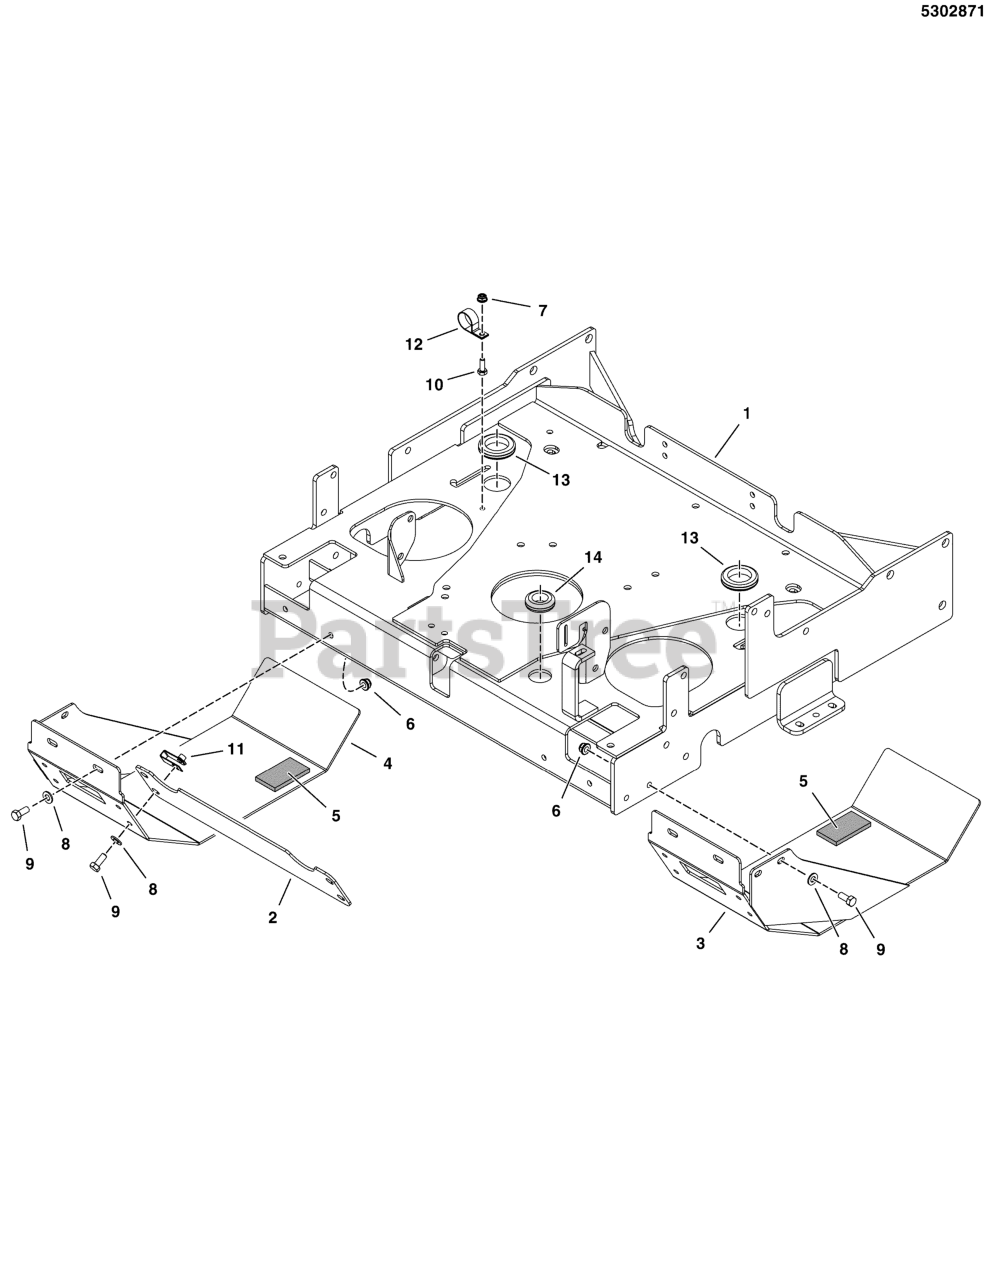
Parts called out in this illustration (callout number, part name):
1	WELD, ENGINE DECK, SW30 - RED
2	PLATE, REAR GUARD, SW30 - RED
3	WELD, SKID PLATE, RH - RED
4	WELD, SKID PLATE, LH - RED
5	PAD, RUBBER MOUNT, 1/4 MAT
6	NUT, 5/16-18 HEX NYLOCK FLANGE
7	NUT, 1/4-20 HEX NYLOCK FLANGE
8	WASHER, 5/16" SAE
9	BOLT, 5/16-18 X 3/4 GD5
10	BOLT, 1/4-20 X 3/4 GD5 YZ
11	BODY CLIP, 5/16-18-7GA MATERIAL
12	CLAMP, VINYL INSULATED
13	GROMMET, 1-1/4
14	GROMMET, 7/8
